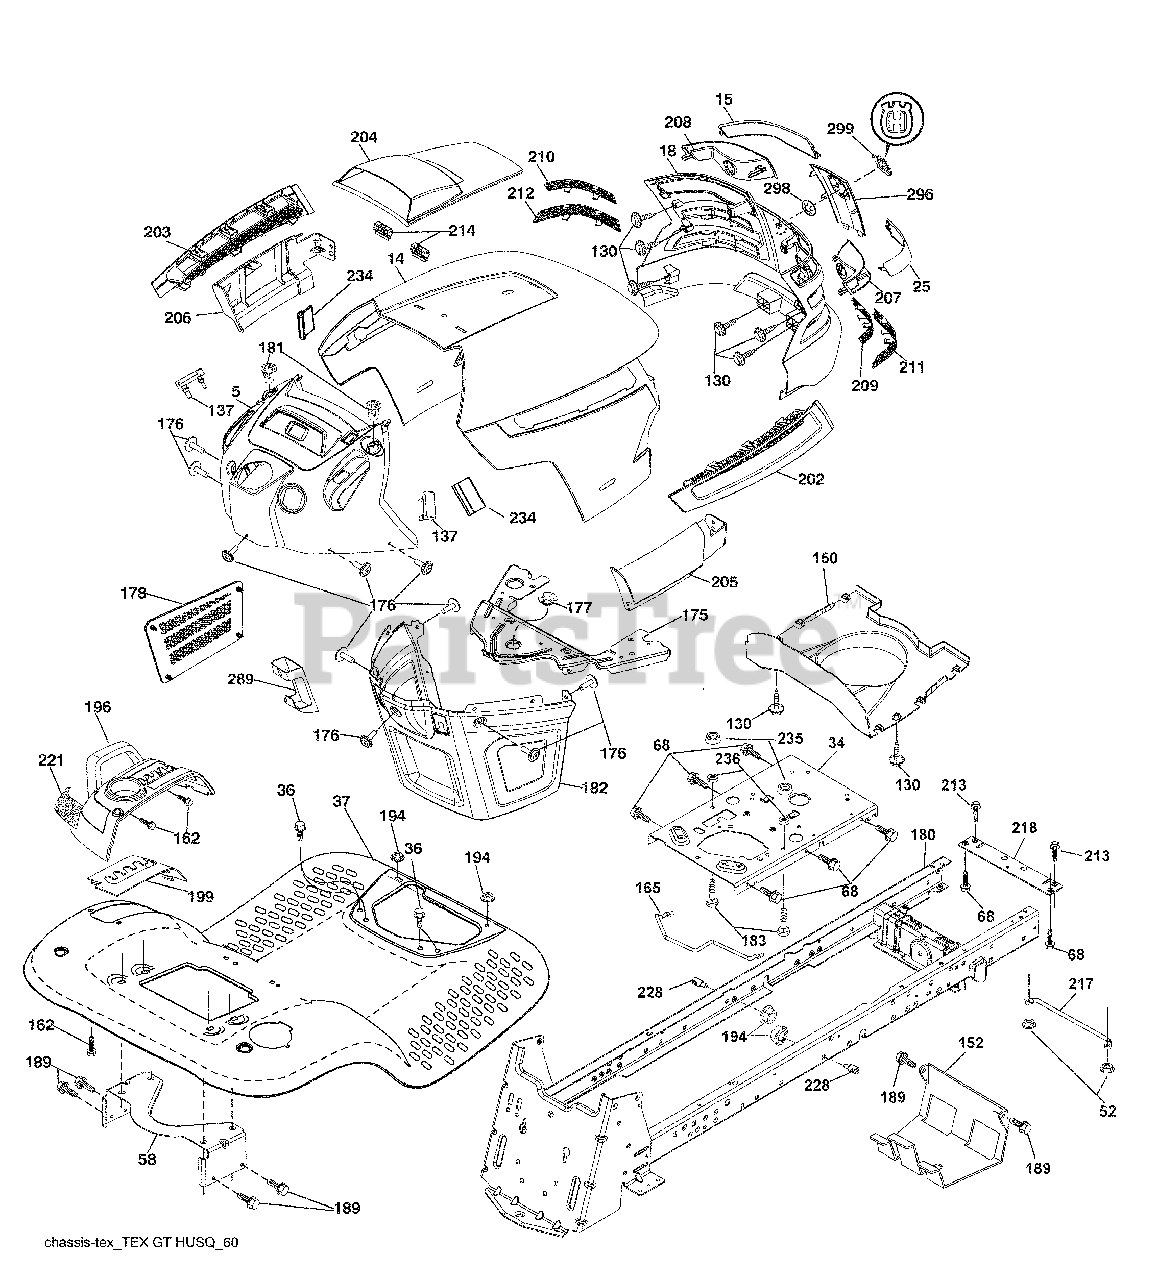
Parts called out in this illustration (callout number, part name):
14	Hood
34	Plate Engine
36	Screw 5/16-18 x 3/4
37	Fender
52	Nut Crown Lock 5/16-18
58	Bracket Fender
68	Screw 5/16-18 x 1/2
130	Screw #10 x 0.750 BOS Thread
137	Bumper Dash
150	Duct Heat Hood
152	Shield Browning/Debris
162	Screw Hex Wsh Hi-Lo 1/4 x 1/2
165	Bracket Support Tank
175	Crossmember
176	Screw 10-24 x 5/8 Wshd Qdrx
177	Bushing Steering
178	Cargo Asm. Net
180	Chassis
181	Bushing MMT Fender
182	Dash Lower
183	Bolt 5/16-18 unc x 1-1/4
189	Screw 5/16-18 x 3/4
194	Nut Lock 5/16-18
196	Console Asm. Deck Lift
199	Plate Deck Lift
202	Vent Side Hood RH
203	Vent Side Hood LH
204	Vent Asm Hood Top
205	Skirt Hood Side RH
206	Skirt Hood Side LH
209	Insert Hex Top RH
210	Insert Hex Top LH
211	Insert Hex Bottom RH
212	Insert Hex Bottom LH
213	Bolt Hex Hd 5/16-18 unc x 3/4
214	Clip Retainer
218	Hood Stop X Piece
221	Reflector LH
228	Stud Fastener
234	Bumper Hood
235	Spacer Fender
236	Nut Center Lock 5/16-18 unc
289	Plug Cruise/Phone
299	Logo
